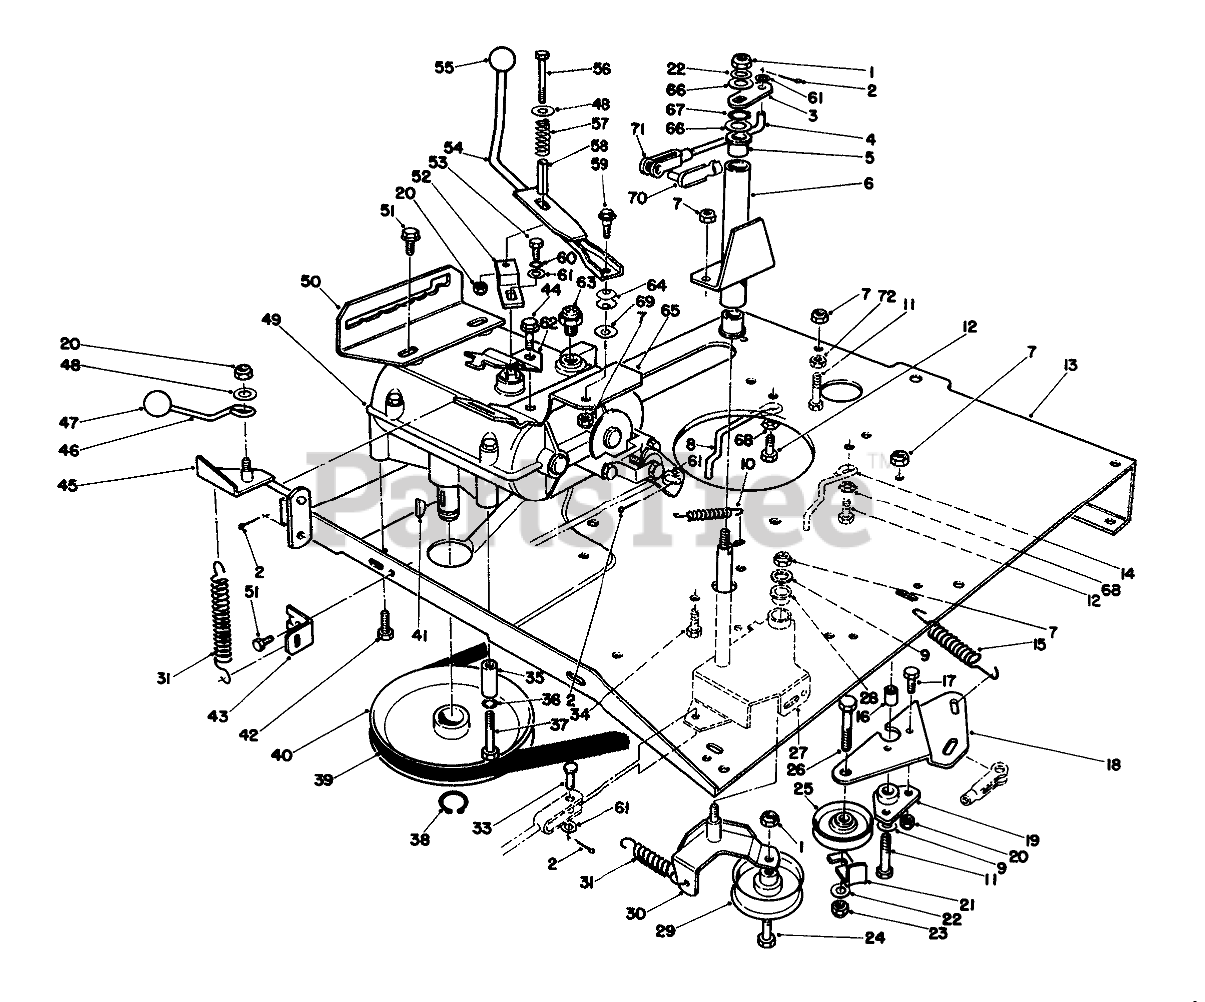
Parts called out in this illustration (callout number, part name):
1	NUT-LOCK, NI
2	PIN-COTTER
3	Flat-Deck Engage
4	LINK-DECK ENGAGE
5	BUSHING-FLANGE
6	Pivot Tube W.A. (Incl. Ref. #5)
7	NUT-LOCK, NI
8	ENG BELT GUIDE R.
9	WASHER-PLAIN
10	SPRING-RETURN, BRAKE
11	SCREW-HH
12	SCREW-HH
13	PLATE-ENGINE
14	GUIDE-ENG. BELT L.
15	SPRING-TRACTION
16	SPACER-PIVOT
17	SCREW-HH
18	Plate-Idler Mount
19	MOUNT-TRACTION PIVOT
20	NUT-LOCK, NI
21	RETAINER-BELT
22	WASHER-FLAT
23	NUT-LOCK, NI
24	SCREW-HH
25	PULLEY-IDLER
26	SCREW-HH
27	Bracket-Idler Arm (Incl. Ref. #28)
28	BUSHING-FLANGE
29	PULLEY-IDLER
30	Idler-Plate, Mount
31	SPRING-IDLER
32	PIN-COTTER
33	PIN-CLEVIS
34	SCREW-HH
35	GUIDE-BELT
36	WASHER-LOCK
37	SCREW-HH
38	RING-SNAP, EXTERNAL
39	67BELT, TRACTION DRIVE
40	PULLEY
41	KEY-WOODRUFF
42	5/16-18 X 5/8 SEMS SC
43	BRKT-SPRING MT
44	SCREW-HWHTF
45	Lever W.A.-Deck Engage
46	ROD-ENGAGE
47	KNOB-CONTROL
48	WASHER-FLAT
49	TRANSMISSION
50	Gate-Shift
51	SCREW-HWHTF
52	LEVER-SHIFT
53	SCREW-HH
54	SHIFT LEVER WA
56	SCREW-HH
57	SPRING-COMPRESSION
58	SPACER-SPLIT
59	SCREW-SHOULDER
60	WASHER-LOCK
61	WASHER-FLAT
62	BRKT-DECK ENG UPPER
63	NEUTRAL SWITCH
64	WASHER-BELLEVILLE
65	BRKT-DECK ENG. SHIFTER
66	WASHER
67	RING-RETAINING
68	WASHER
69	THRUST WASHER
70	CLEVIS PIN ASM
71	CLEVIS-ADJ
72	NUT-JAM
